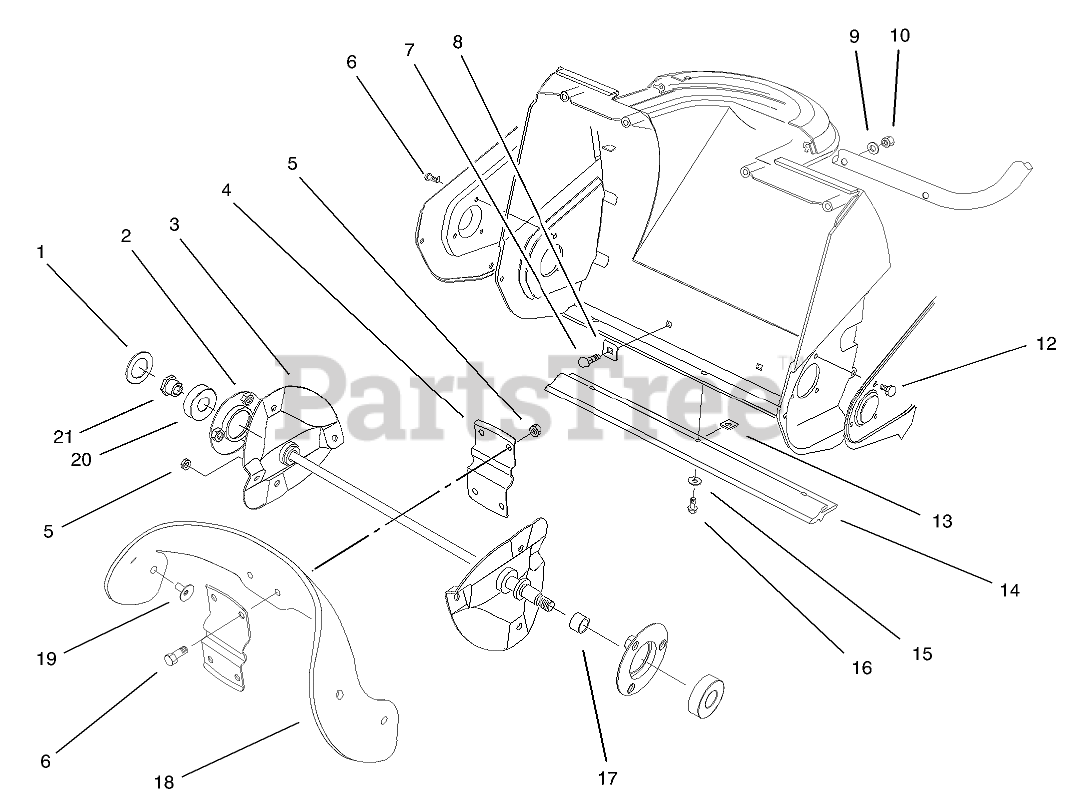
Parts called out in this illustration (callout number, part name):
1	WASHER-RUBBER
2	FLANGE BEARING ASM
3	ROTOR SHAFT ASM
4	SUPPORT-ROTOR
5	NUT-LOCK, NI
6	SCREW-HHF
7	SCREW-CARR
8	WASHER-SQUARE
9	WASHER
10	NUT-LOCK, NI
12	SCREW-HH
13	NUT-CLIP, U
14	SCRAPER
15	WASHER-FLAT
16	SCREW-HWHTF
17	SPACER
18	BLADE-ROTOR
19	SCREW
20	BEARING-BALL
